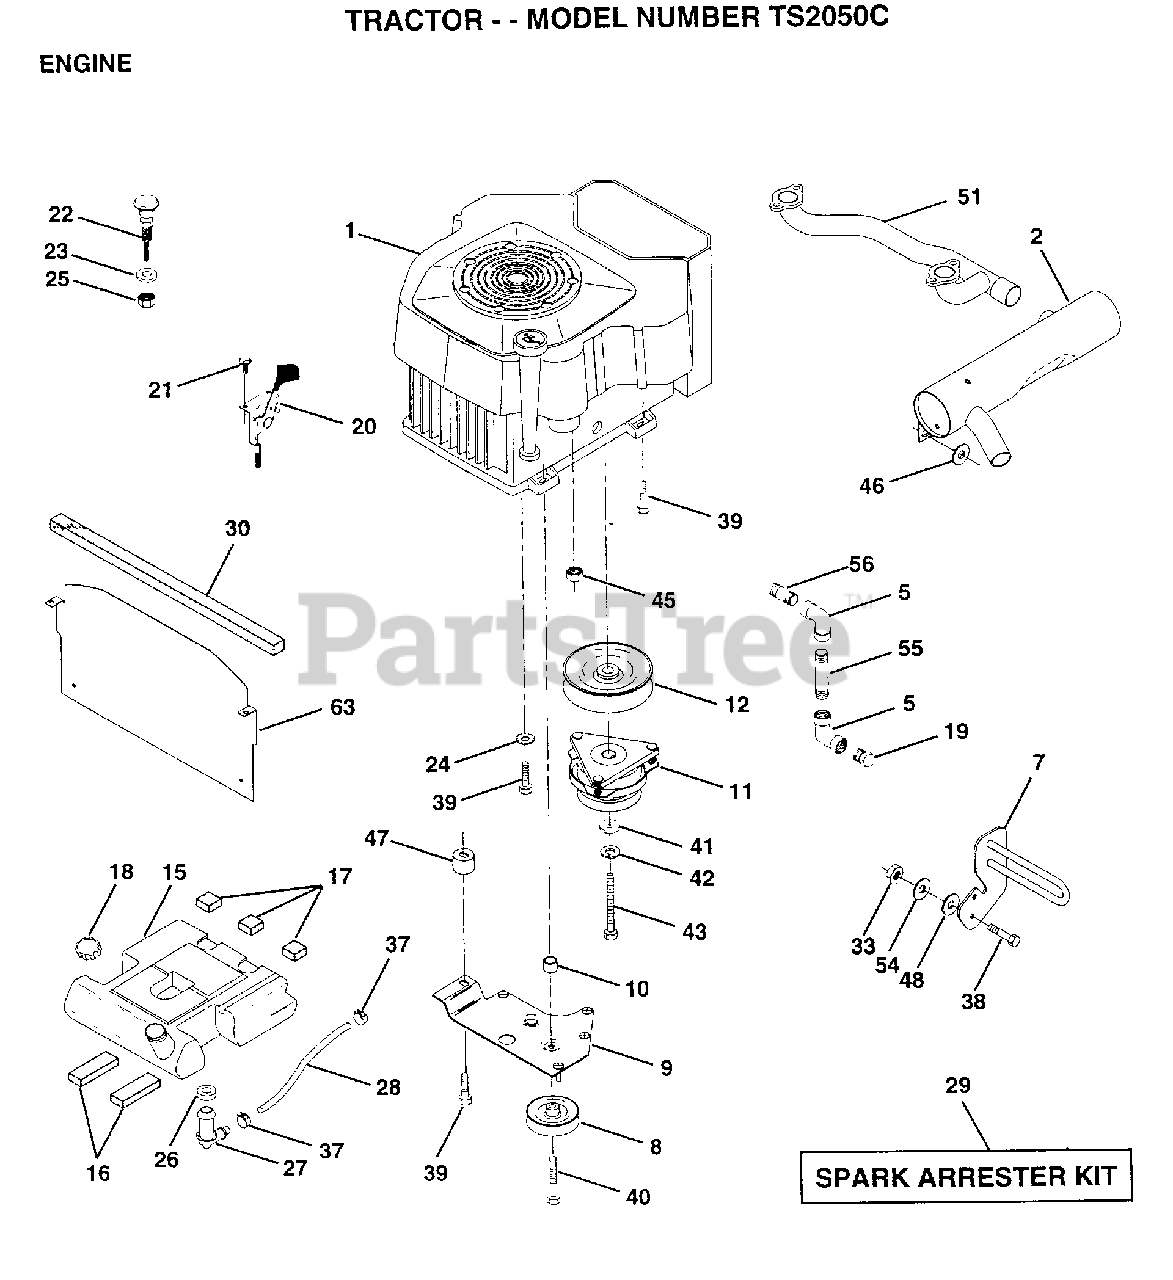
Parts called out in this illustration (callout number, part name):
1	ENGINE, KOHLER
5	ELBOW
7	GUARD.MUFFLER.ASM
9	KEEPER ASM BELT
10	BUSHING.
12	PULLEY.ENG.CLUTCH
15	TANK FUEL REAR
16	PAD IDLER TI
17	PAD-SPACER LT
18	CAP ASM FUEL
19	PLUG T
21	SCREW LT
22	CHOKE CONTROL
23	WASHER
24	LOCKWASHER
25	"NUT,KEPS 3/8-24IM"
26	BUSHING OUTLET T
27	STEM.TANK.FUEL
29	SPARK ARREST KIT
30	FOAM-STRIP LT
33	NUT
37	HOSE CLAMP
38	"BOLT,HEX"
39	SCREW.3/8-16X2.25
40	SCREW.TT.3/8-16X4
41	WASHER
42	LOCKWASHER
43	BOLT.7/16-20X4.25
45	NUT
46	WASHER HYT
47	SPACER.ENGINE
48	WASHER T
54	WASHER
56	NIPPLE.PIPE
63	HEAT.SHIELD.VGT.
